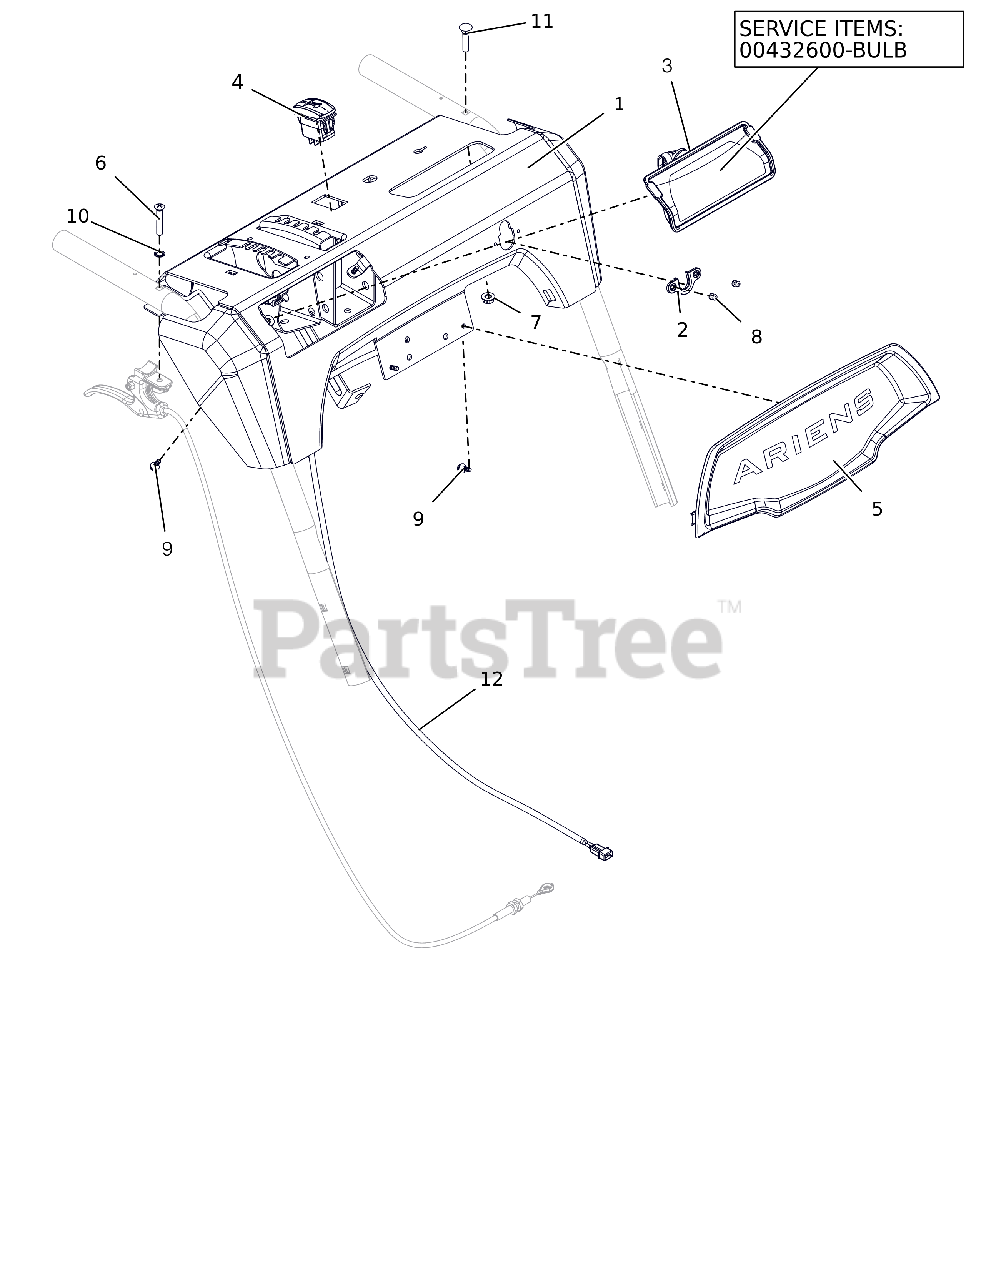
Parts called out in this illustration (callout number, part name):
1	CONTROL PANEL W/DECAL FRIC-TRK
2	GROMMET, CABLE, QUICK TURN 2
3	HEADLIGHT ASY, HALO 20W 2SHOT
3	BULB, LIGHT-HALOGEN 20W
4	SWITCH,ROCKER SPST-ON/OFF
5	BEZEL, DASH - ARIENS LG DASH
6	SCR-MCH .25-20X1.50 OVAL HD
7	@NUT-LK-CTR-FLG .25-20 YWZC
8	RVT-POP #43 .125X.313 STL ZINC
9	SCR-TAP #10X.50 BOSS INDHXHD
10	WSHR-LK-INT .250 TH TYA
11	BLT-RDHDXLSQNK.25-20X1.25 G5ZC
12	HARNESS, LIGHT & WARMER
